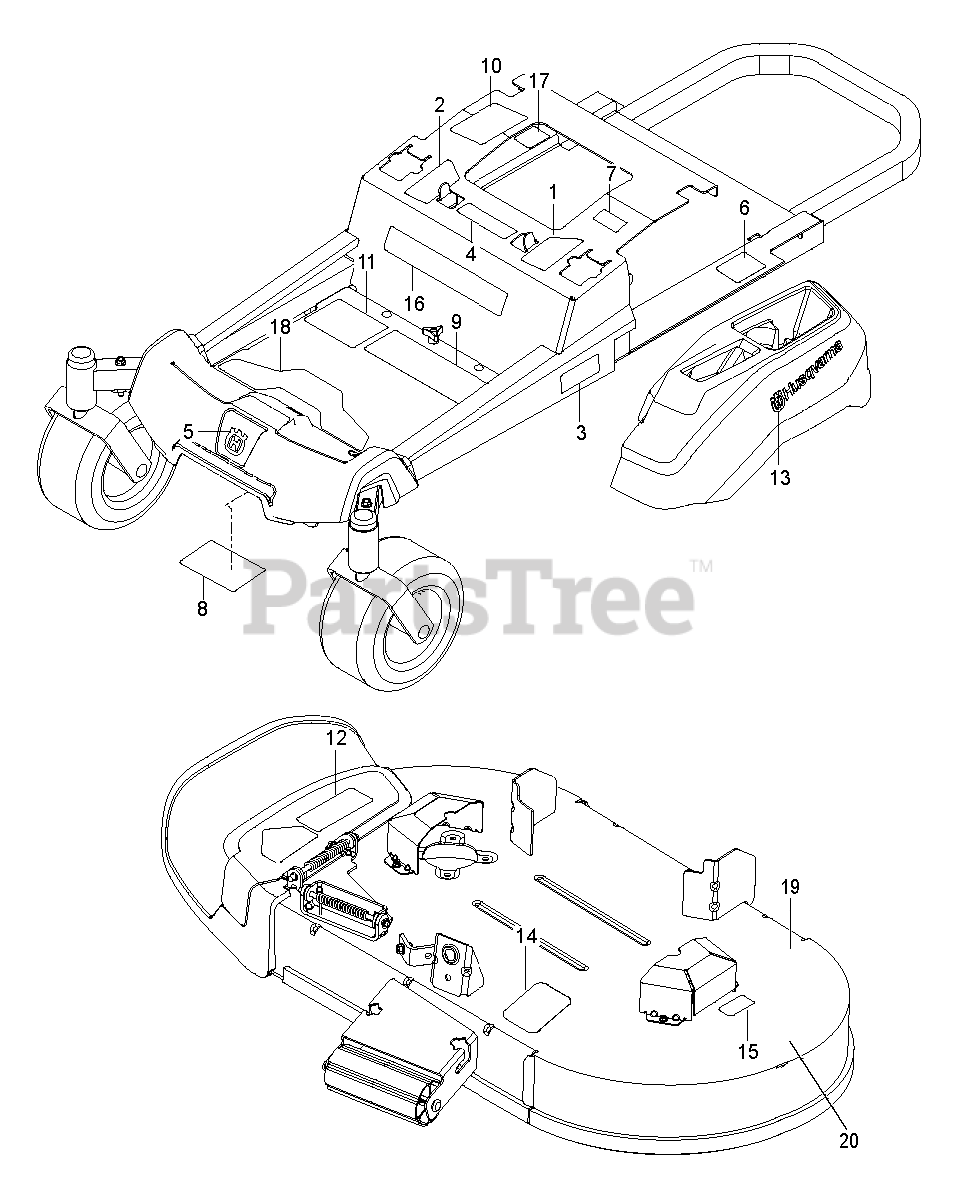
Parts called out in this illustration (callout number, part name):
1	DECAL.ZTR.RZ.THRTL/PRKBRK.V2.L
2	DECAL.ZTR.RZ.THRTL/PRKBRK.V2.R
3	DECAL.ZTR.SIDRAIL.Z242F.HUS
4	EURO DECAL-BATTERY WARNIN6
5	DECAL.BADGE.55MM.CROWNH.HUSQ
6	DECAL, DO NOT TOW
7	DECAL, EXITING MOWER
8	DECAL, SERVICE
9	DECAL ZTR WARNING DECAL DECAL.
10	DECAL.WARNING.CUST.RESP.E85.
11	DECAL.ZTR.STARTINSTRCT.CHOKE15
12	DECAL.TRACT/ZTR.DECKWARN.HUSQ
13	DECAL.HUSQVARNA.210MM
14	DECAL, BELT ROUTING
15	DECAL.DECK.CLEARCUT.NOSTEP
16	DECAL ZTR BRAND GRAPHIC DECAL.
16	DECAL CERTIFICATION DECAL EMCC
17	DECAL.80.DBA.AUSTRALIA
18	DECAL.EPA.EMISS.LABEL.ZTR.18
18	PAD.RZ.FOOTREST.PLATE
19	DECAL DECK DECAL DECAL.DECK.WA
20	DECAL DECK DECAL DECAL.42DECK.
